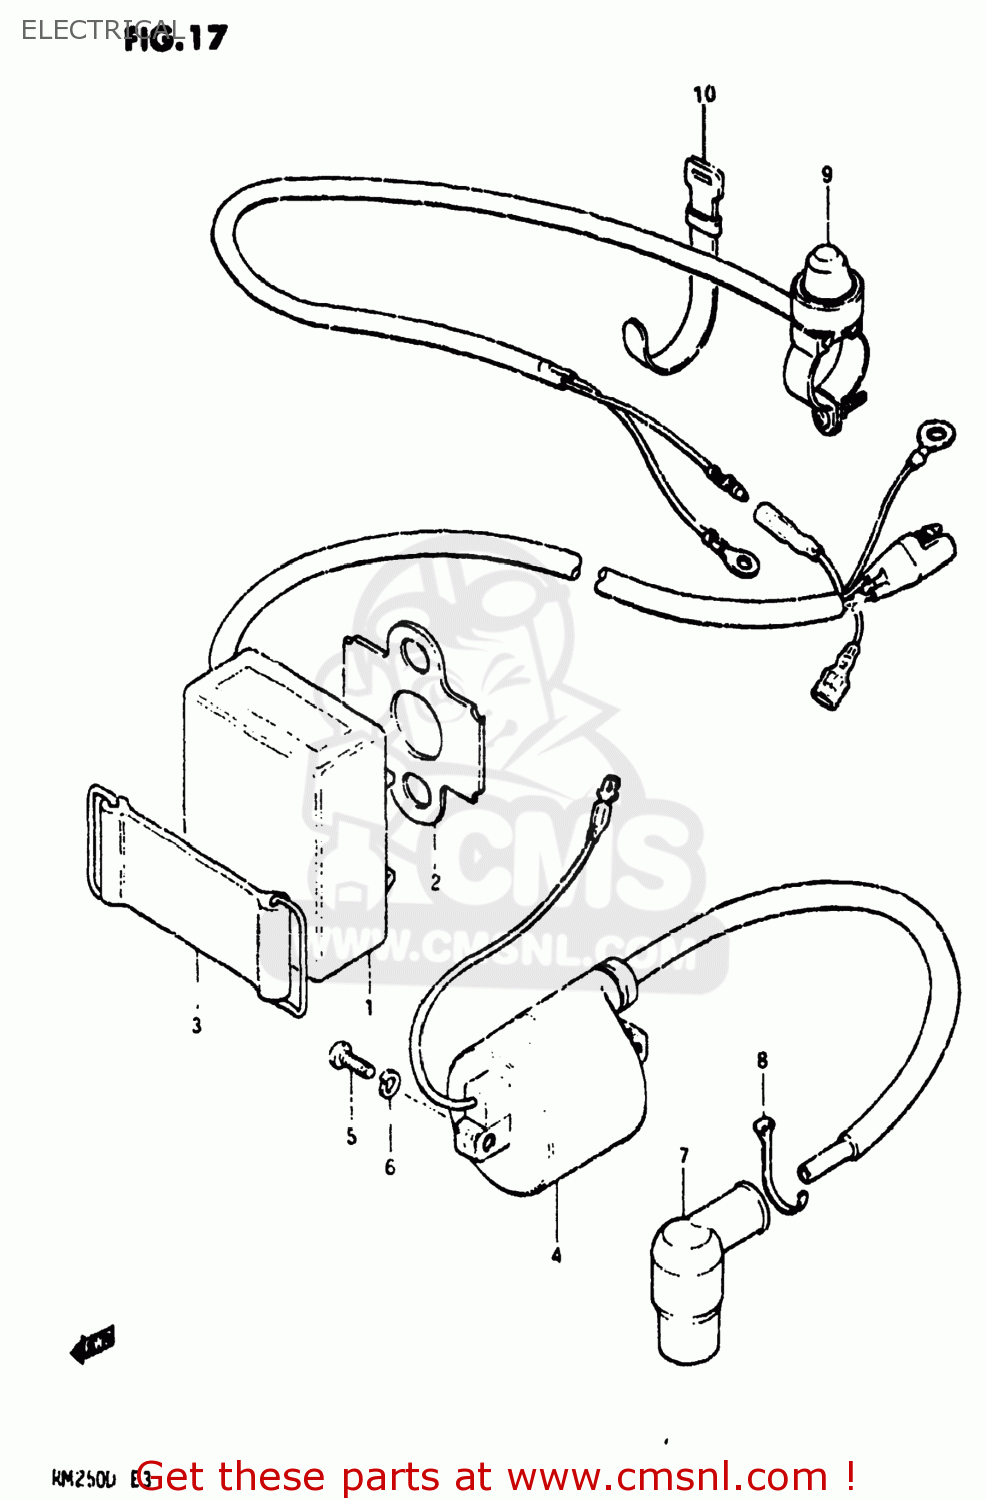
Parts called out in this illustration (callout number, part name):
1	CDI UNIT
2	PROTECTOR,CDI UNIT
3	BAND
4	COIL ASSEMBLY,IGNITION
5	SCREW
6	LOCK WASHER
7	CAP,SPARK PLUG
8	CLAMP
9	SWITCH ASSEMBLY
10	CLAMP(L:120)
